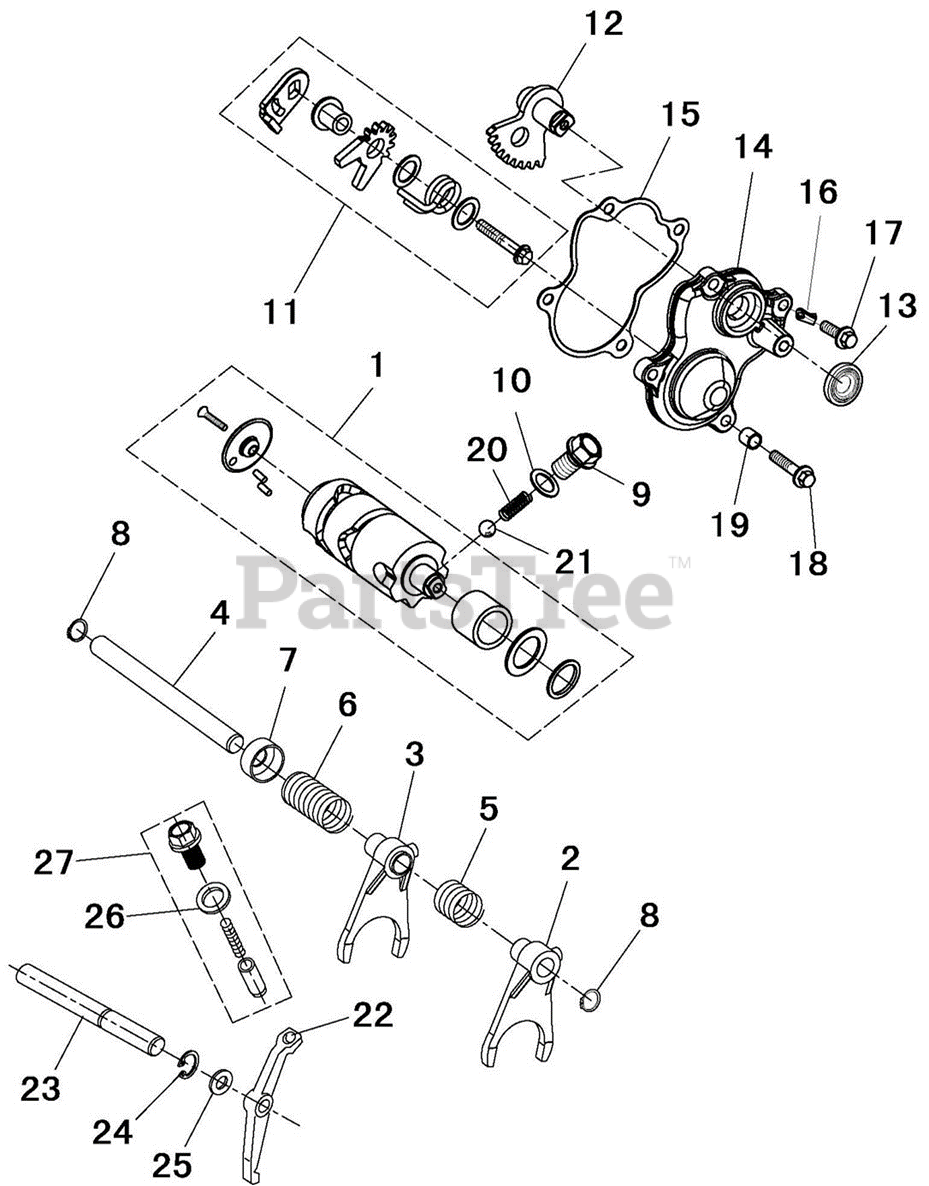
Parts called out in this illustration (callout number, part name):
1	SHIFT DRUM
2	SHIFTING FORK I
3	SHIFT FORK
4	SHIFT SHAFT
5	REVERSE GEAR SPRING
6	HIGH/LOW GEAR SPRING
7	SHIFT RAIL SPRING SEAT
9	HOLLOW BOLTS M14X1.5X21
10	COPPER WASHER 14X21X1
11	SHIFT DIAL PLATE
12	SHIFT SHAFT ASSEMBLY
13	OIL SEAL 15X25X5
14	SHIFT SHAFT COVER
15	SHIFT SHAFT COVER GASKET
16	CLAMP
17	HEX FLANGE BOLTS M6X20
18	HEX FLANGE BOLTS M6X30
19	DOWLE PIN 8X12
20	SPRING 24X1
21	STEEL BALL 9.5
22	PARKING ARM
23	PARKING ARM SHAFT
25	WASHER 12.3 x 20 x 1
26	COPPER WASHER
27	PARKING BOLT ASSEMBLY
